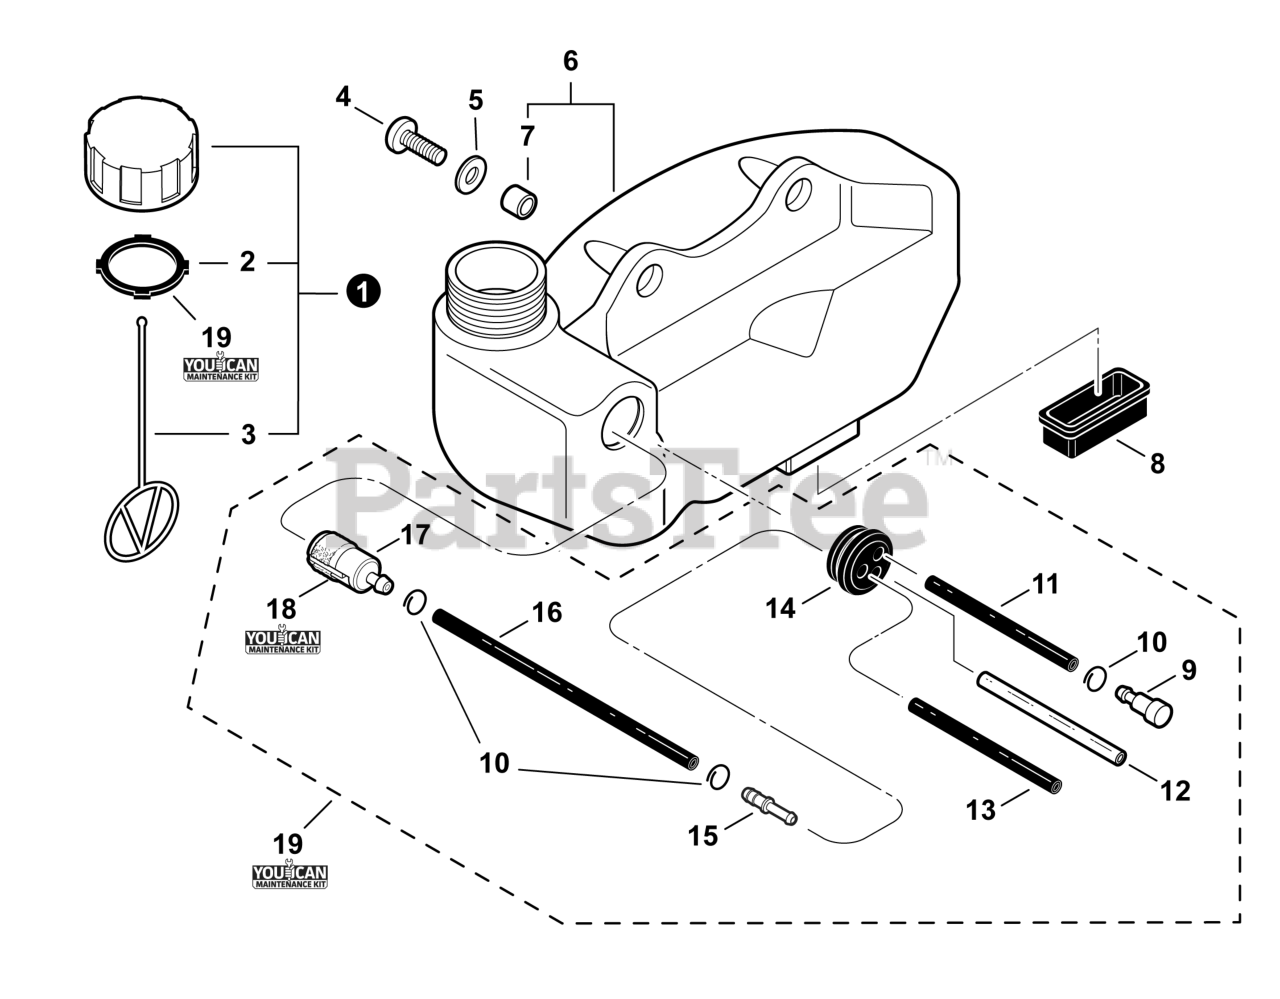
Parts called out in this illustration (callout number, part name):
1	CAP ASSY, FUEL
2	GASKET, FUEL CAP
3	CONNECTOR, CAP L= 123
4	BOLT, TORX 5×16
5	WASHER 5.5×12×0.8
6	TANK ASSY, FUEL
7	SPACER 6.2×7.8×6
8	CUSHION, FUEL TANK
9	VENT ASSY
10	CLIP Ø6
11	PIPE, FUEL 3×5×70 BLACK
12	PIPE, FUEL 3×6×75 CLEAR
13	PIPE, FUEL 3×5×74 BLACK
14	GROMMET, FUEL Ø5
15	CONNECTOR, PIPE Ø5ר3.5
16	PIPE, FUEL 3×5×115
17	FILTER, FUEL
18	TUNE-UP KIT - YOUCANT
19	FUEL SYSTEM KIT - YOUCANT
